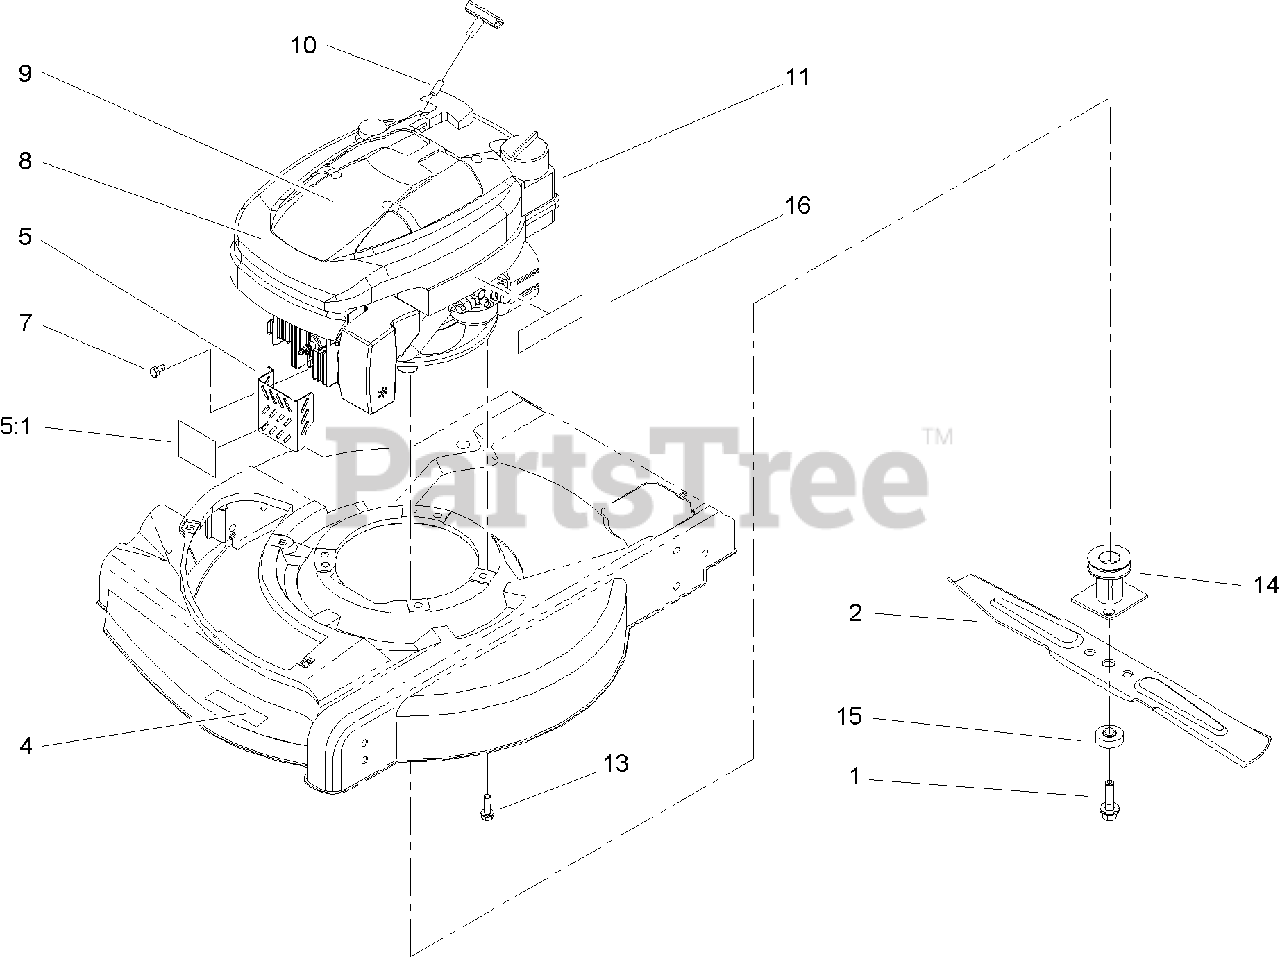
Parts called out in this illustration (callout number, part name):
1	BOLT-BLADE
4	DECAL-DECK
5	MUFFLER GUARD ASSEMBLY
5:1	DECAL-SURFACE, HOT
7	SCREW-HWH
8	APPLIQUE
9	DECAL-RECOIL
10	STOP-ROPE
13	SCREW-TAPTITE
14	DRIVER-BLADE
16	DECAL-PRIMER
